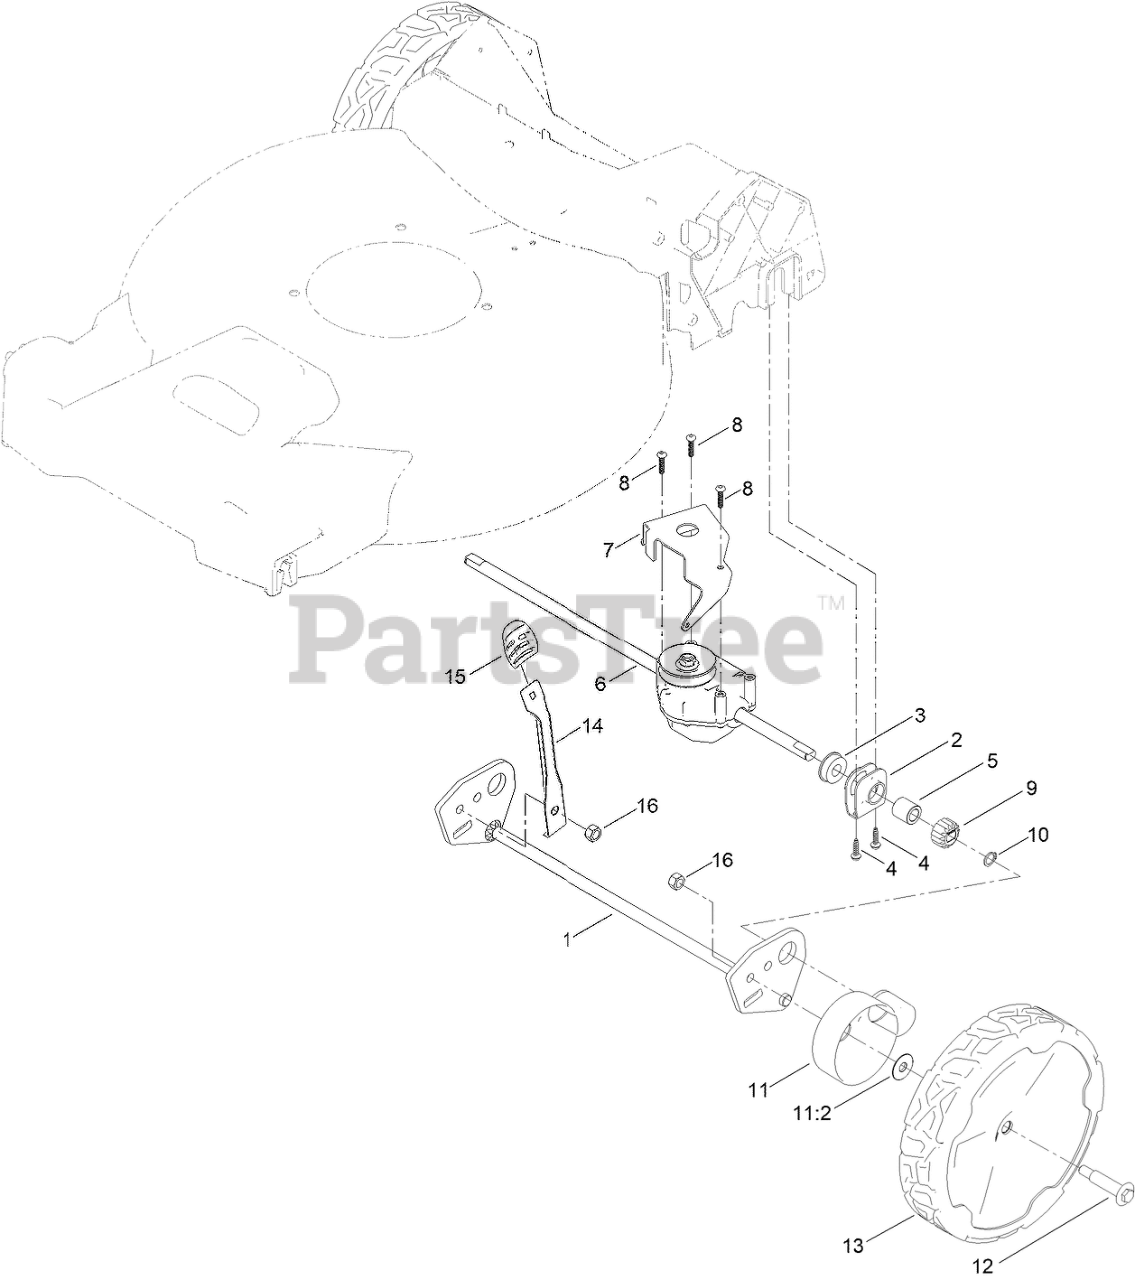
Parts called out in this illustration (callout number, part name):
1	AXLE-REAR, WA
2	RETAINER-BEARING
3	BEARING-BALL
4	SCREW-HWH
5	BUSHING-SLEEVE
6	TRANSMISSION (7:1 RATIO)
7	BRACKET-TRANSMISSION
8	SCREW-PLASTITE
9	GEAR-PINION, 15T
10	RING-RETAINING
11	ASM-COVER, GEAR (DK GRAY)
11:2	WASHER-STEPPED
12	BOLT-SHOULDER
13	ASM-9.65" WHEEL, GEARED
14	ARM-SPRING
15	KNOB-LEVER, HOC
16	LOCKNUT
